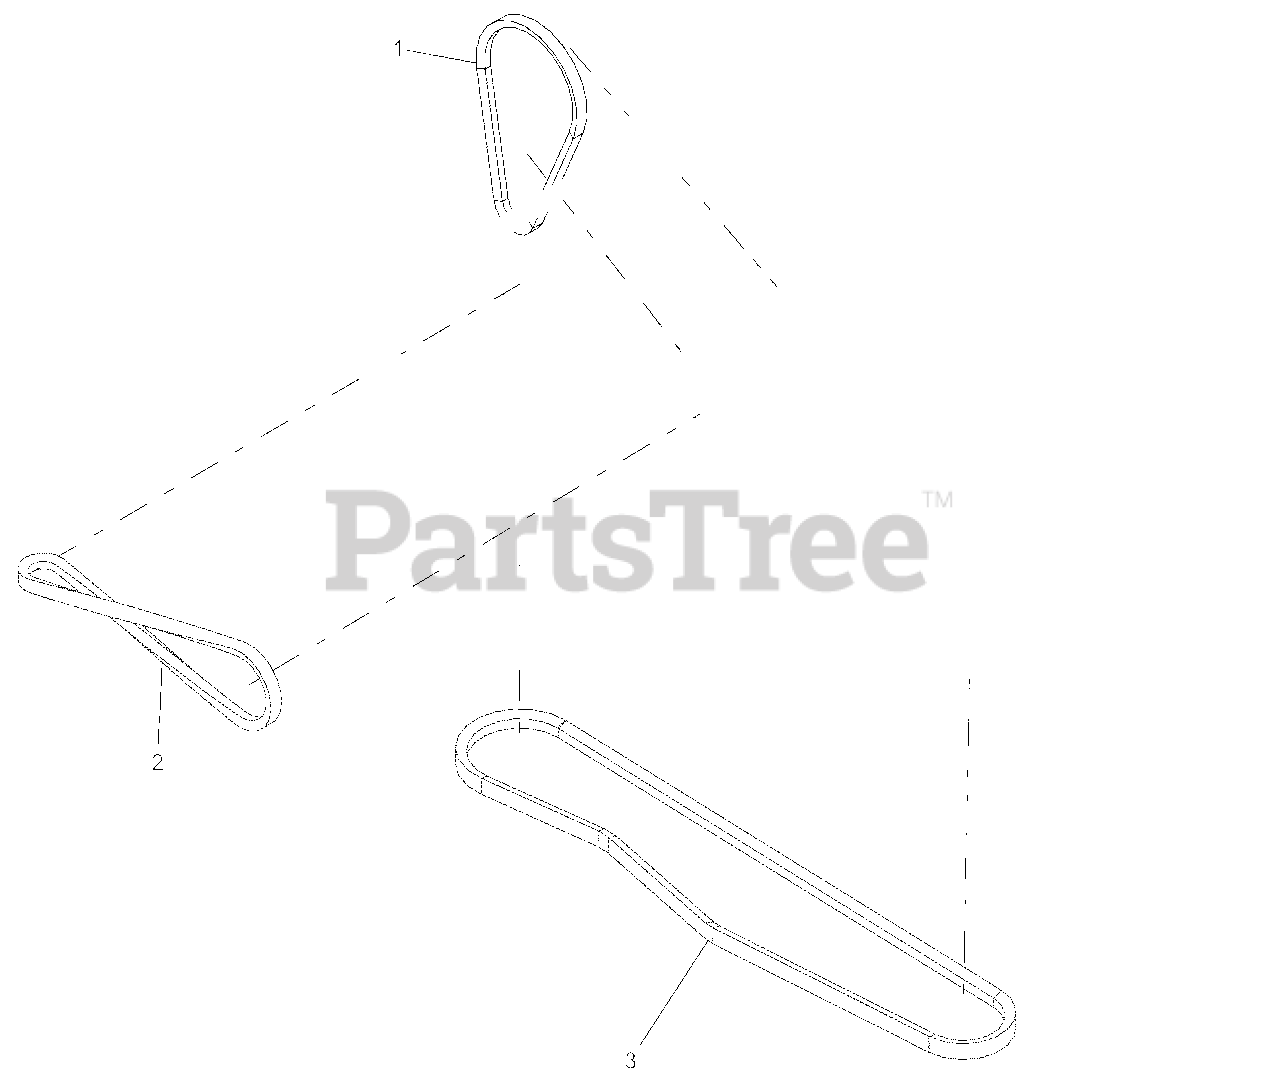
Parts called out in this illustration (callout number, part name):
1	V-BELT, 4L-RAW EDGE
2	V-BELT, 4L-RAW EDGE
3	V-BELT, 5L-WRAPPED
